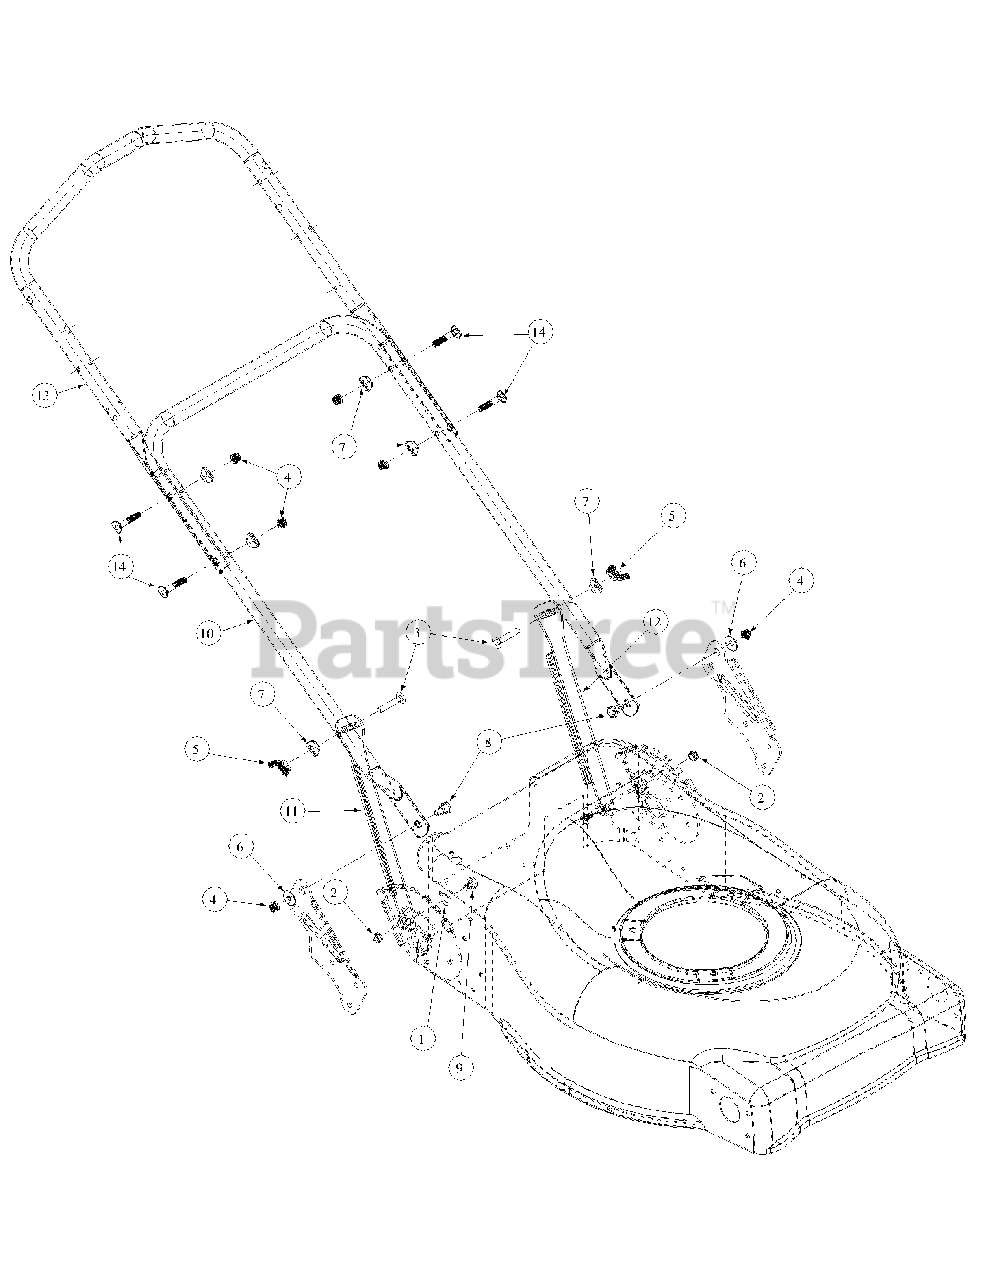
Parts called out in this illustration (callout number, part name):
1	Thrust Washer
2	Nut, Lock, 5/16-18,
3	Bolt Carriage, 5/16-18, 1.75
4	Hex Nut, 5/16-18
5	Wing Nut, 5/16-18
6	Belle Washer, .325 x .930 x .045
7	Shoulder Washer, .320 ID x .93 OD
8	Shoulder Screw, .435 x .350, 5/16-18
9	Shoulder Screw, .437 x 1.62 LG
10	Handle, Lower, 1.0"
11	Strut, 3 Position Handle, Right hand
12	Strut, 3 Position Handle, Left hand
13	Upper Handle, 1.0", Self Propelled
14	Carrige Bolt, 5/16-18 x 2.0 CRVD
